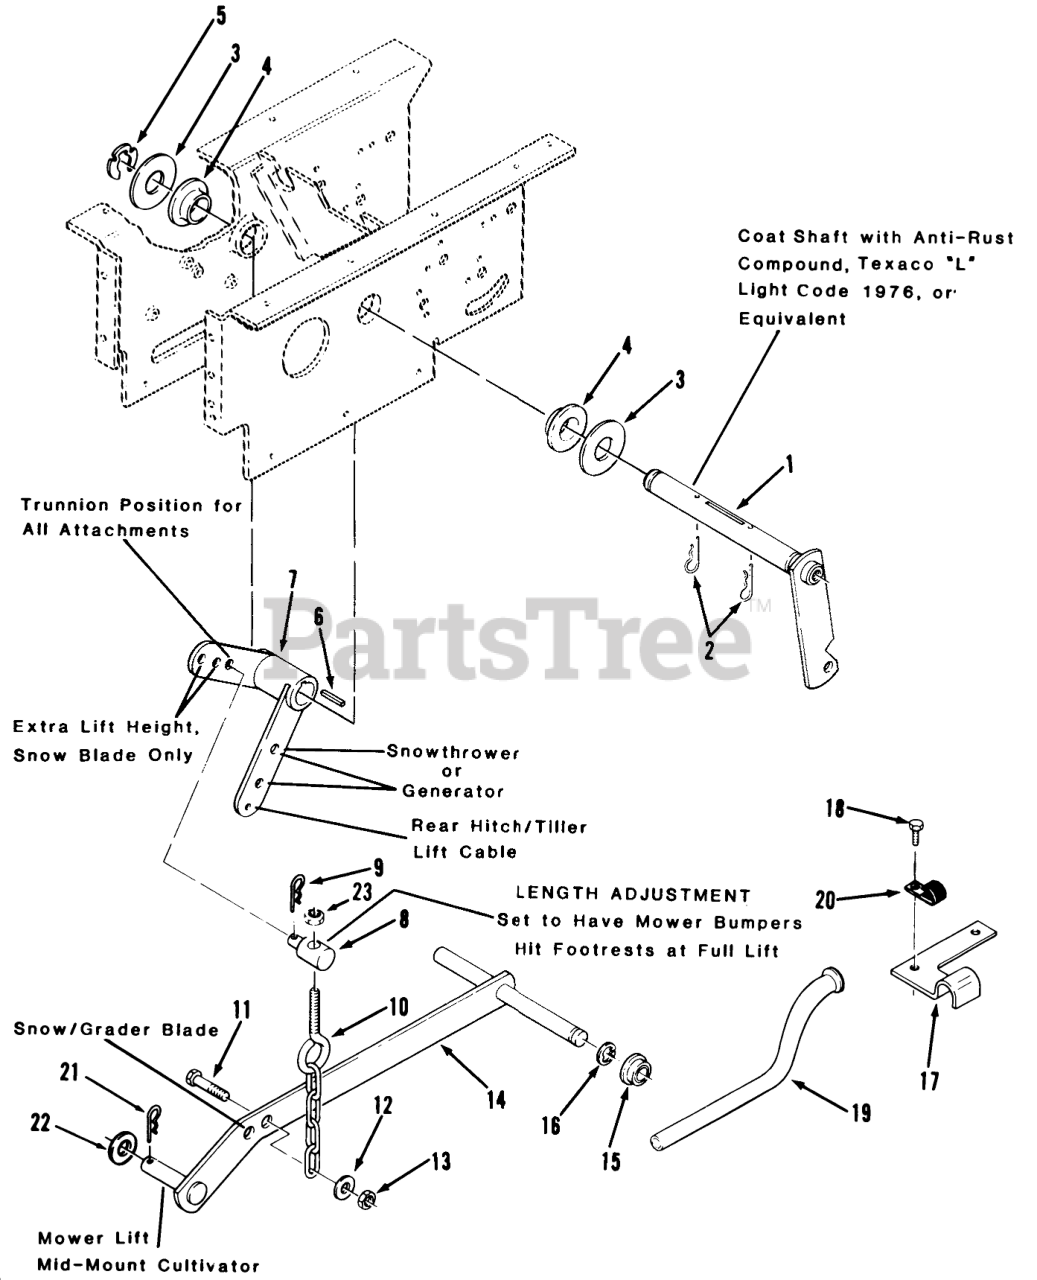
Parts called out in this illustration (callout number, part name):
1	WLDMT-LIFT ARM
2	Pin-Cotter
3	WASHER
4	BEARING-FLANGE
5	Retainer
6	KEY-SQUARE
7	LIFT LEVER ASM
8	TRUNNION-LIFT
9	Hairpin Cotter
10	CHAIN-LIFT
11	SCREW-HH
12	WASHER-PLAIN
13	NUT-LOCK, NI
14	ASSY LIFT BAR R
15	BUSHING
16	RING-RETAINING, EXTERNAL
17	CLAMP-CONDUIT R
18	SCREW-HH, LOCK
19	TUBE-CONDUIT R
20	CLIP
21	Hairpin Cotter
22	Washer
23	NUT-LOCK, NI
